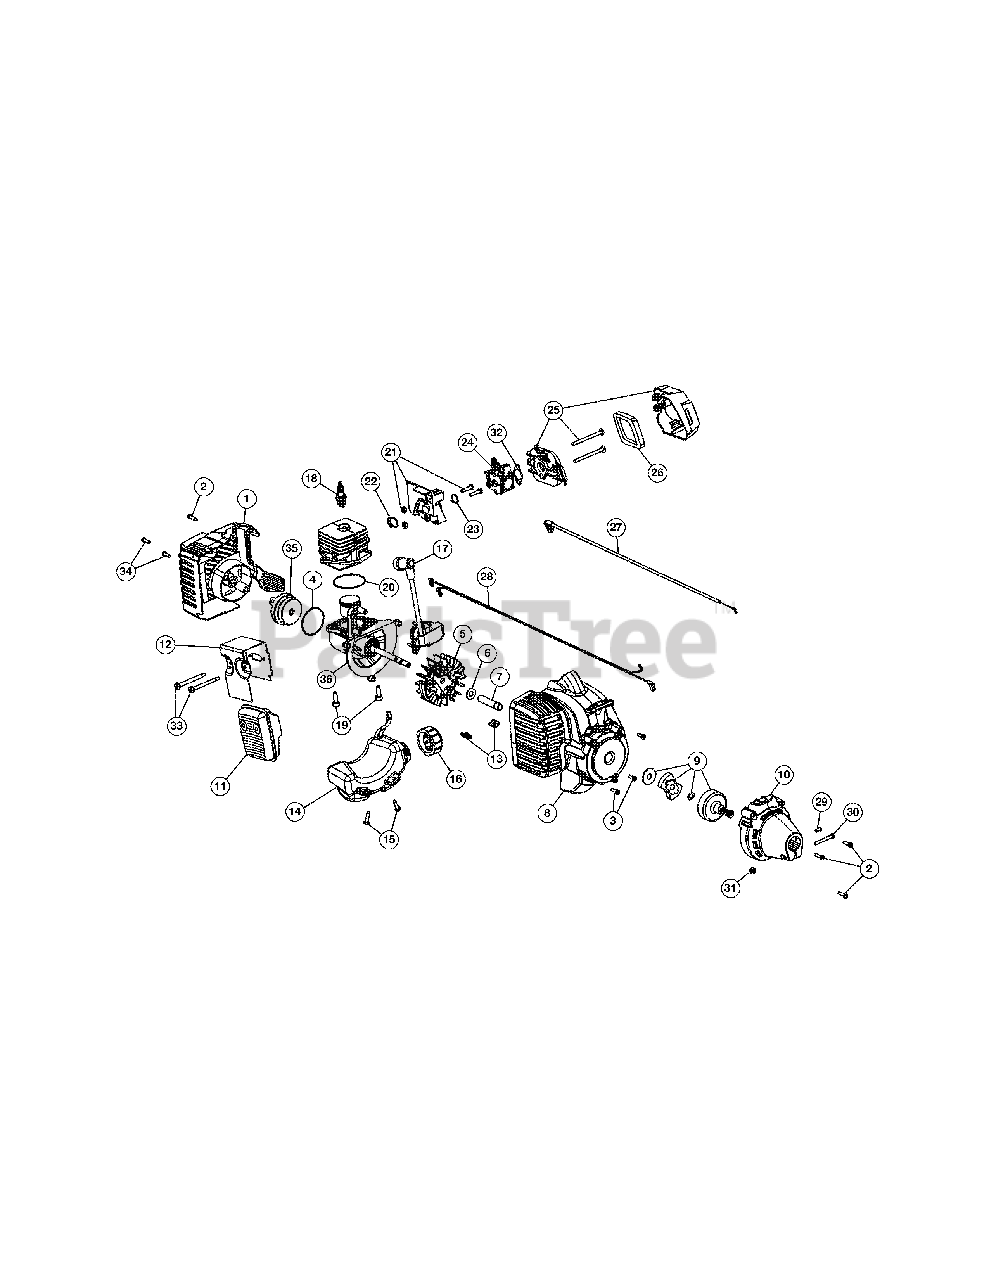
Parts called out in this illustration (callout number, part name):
1	Rear Cover Assembly (includes 2 & 34)
2	Cover Screw
3	Housing Screw
4	O-Ring
5	Flywheel Assembly
6	Washer
7	Spacer
8	Starter Housing (includes 3 & 13)
9	Clutch Assembly
10	Clutch Cover (includes 2)
11	Muffler Assembly (includes 12 & 33)
12	Muffler Gasket
13	U-shaped Nut
14	Fuel Tank Assembly (includes 15 & 16)
15	Tank Screw
16	Fuel Cap
17	Module Assembly
18	Spark Plug
19	Crankcase Bolt
20	Crankcase O-Ring
21	Insulator Assembly (includes 22 & 23)
22	Insulator O-Ring
23	Carburetor O-Ring
24	Carburetor
25	Aircleaner Cover Assembly (includes 26)
26	Aircleaner Filter
27	Throttle Cable
28	Lead Wires
29	Anti-rotation Screw
30	Clamp Screw
31	Clamp Nut
32	Air Cleaner Gasket
33	Muffler Screw
34	Rear Housing Screw
35	Electric Starter Cover Assembly
